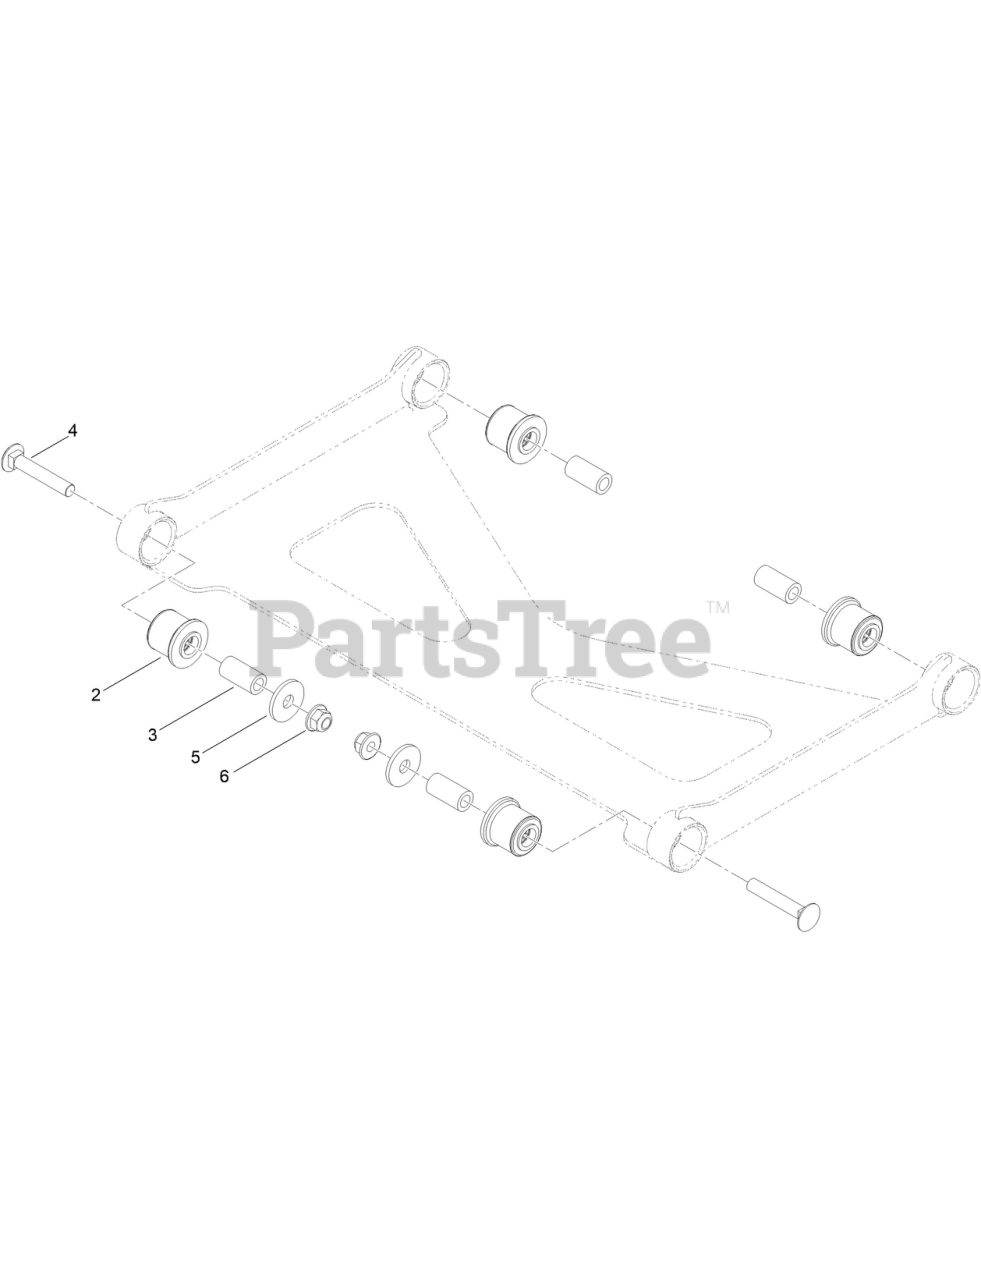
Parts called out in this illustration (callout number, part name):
2	BUSHING-RUBBER, SUSPENSION
3	SPACER
4	SCREW-CARR
5	WASHER
6	NUT-HF, NI
